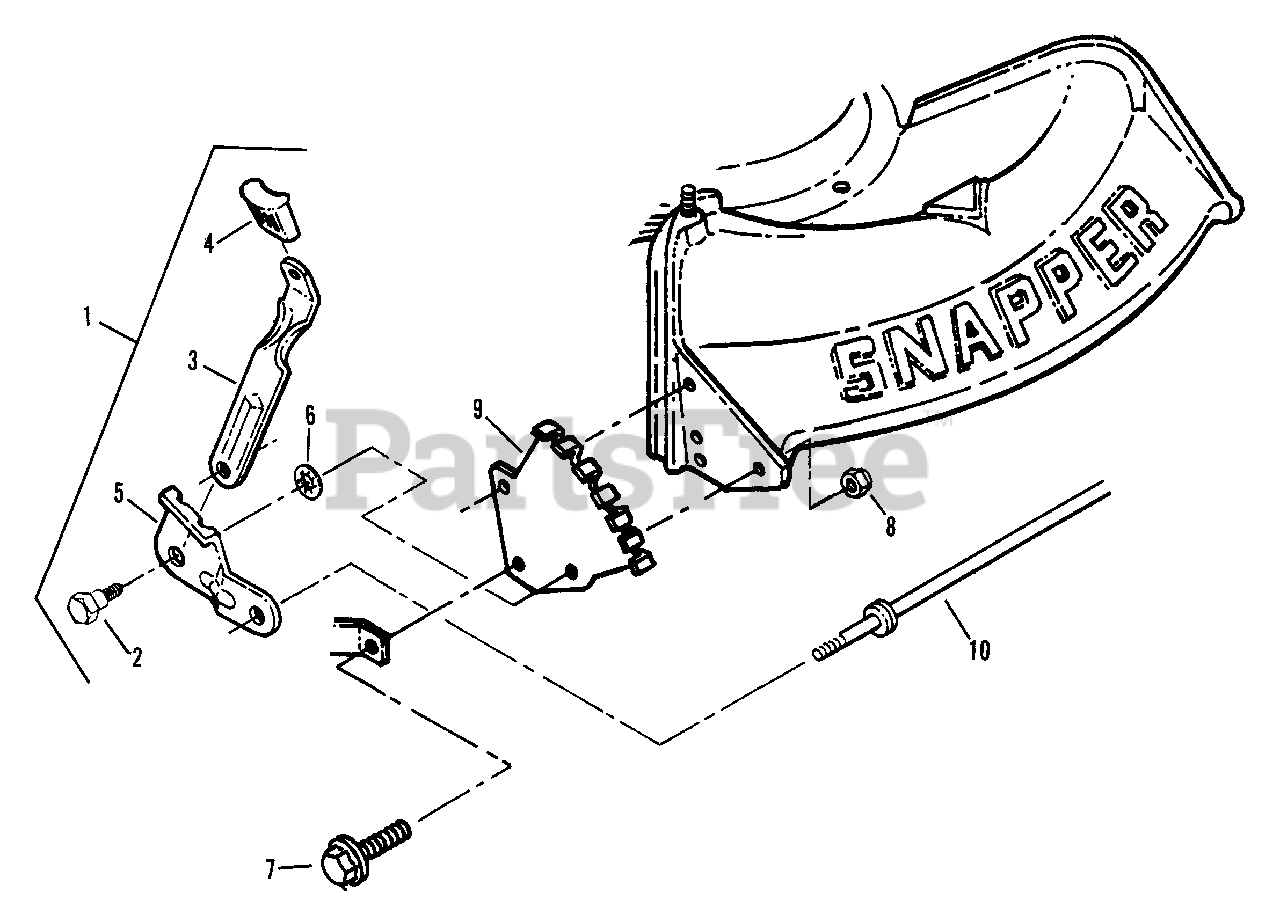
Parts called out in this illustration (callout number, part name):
1	ASSEMBLY, Wheel Arm (LR)
2	BOLT, 5/16 x 1" Shoulder
3	LATCH, Height
4	GRIP, Latch
5	ARM, Right Wheel
6	RETAINER, 5/16 Bolt
7	SCREW, 5/16-18 x 5/8" Self-Tapping
8	NUT, 5/16-18 Hex
9	BRACKET, Front Wheel
10	AXLE
